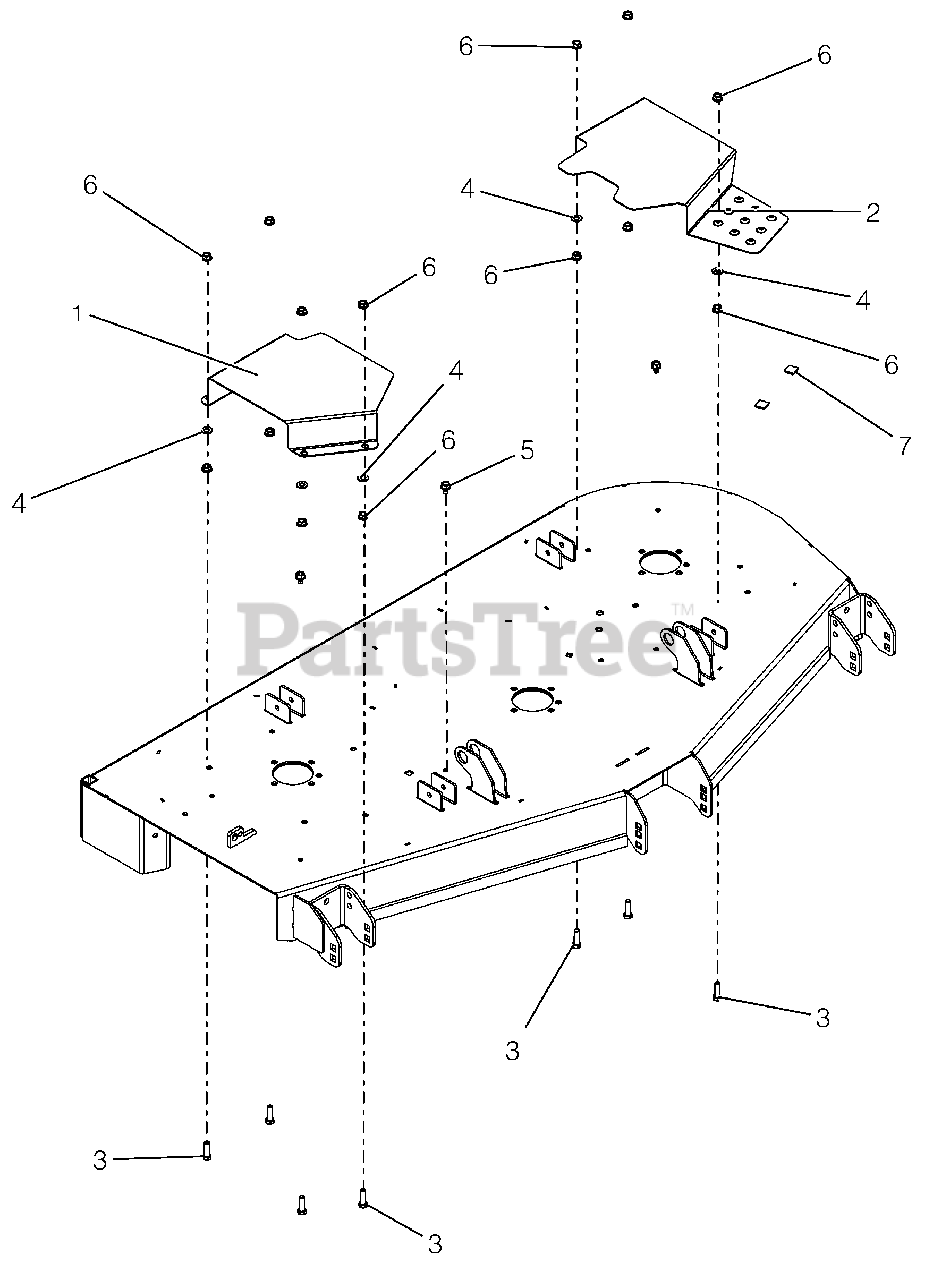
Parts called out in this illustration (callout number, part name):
1	COVER, BELT 52" & 60" RIGHT
2	COVER, BELT 52" LEFT
3	@BLT-HEX .38-16X1.25 GR5 YWZC
4	@WSHR-FL-STL.406X.812X.065 YWZ
5	@SCR-TAP .38-16X.50 HWH TR YWZ
6	@NUT-SPNLK-FLG .375-16 YWZC
